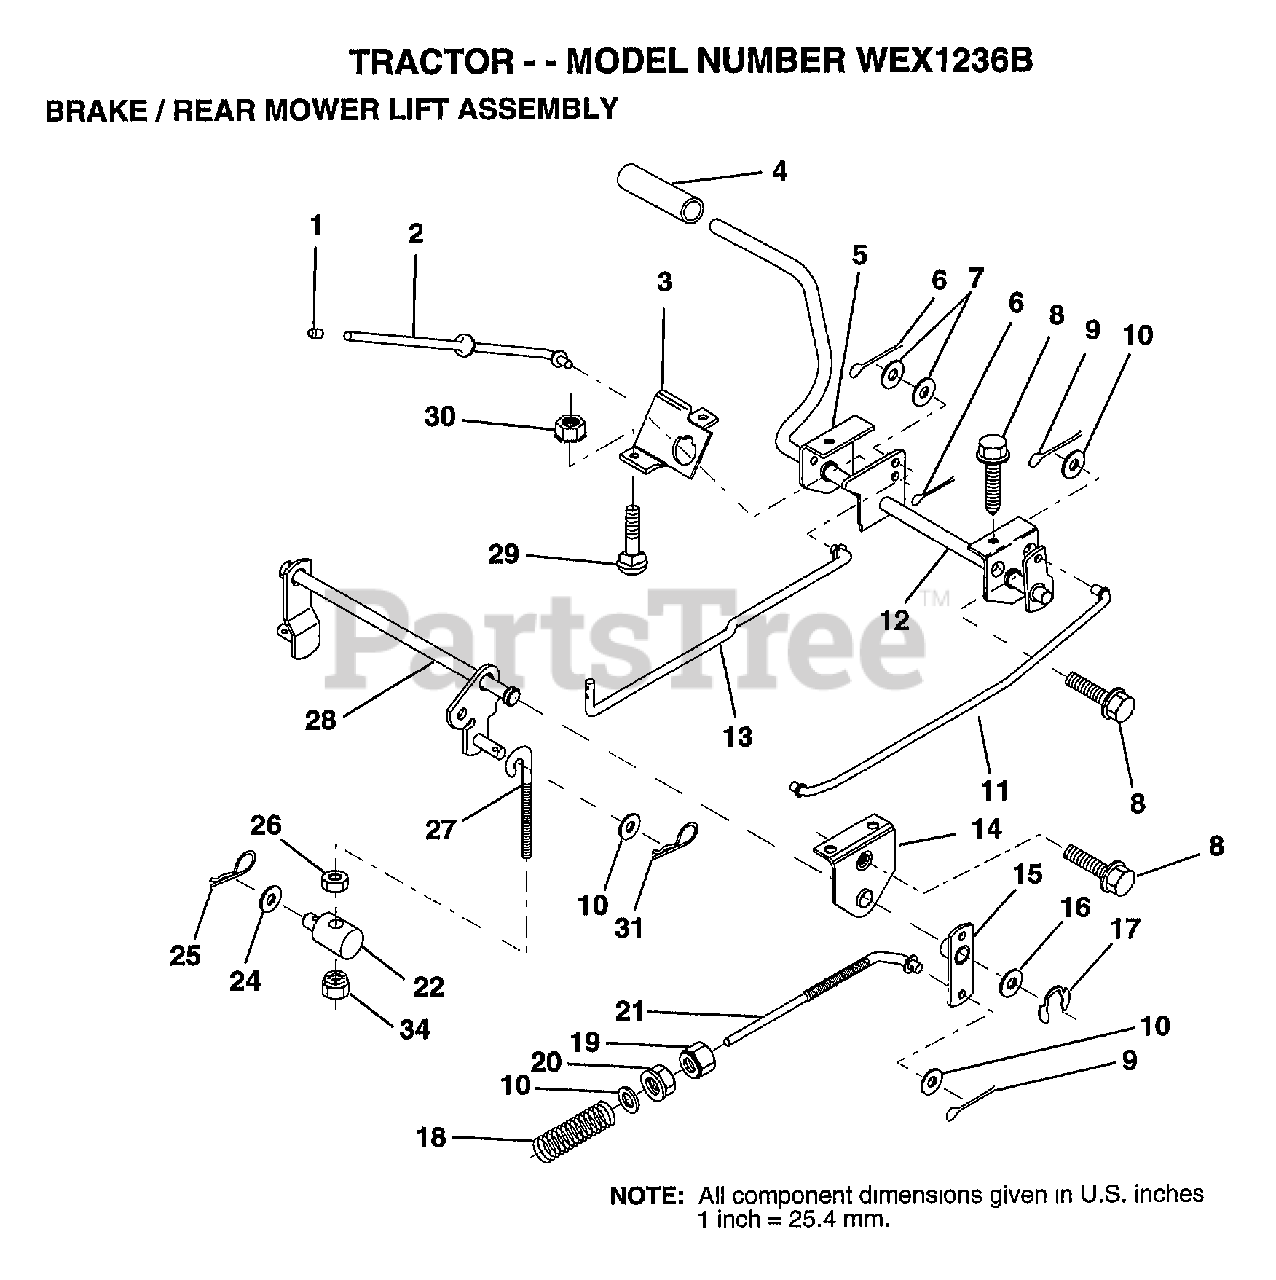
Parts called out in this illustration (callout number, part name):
1	PLUNGER CAP T
2	"ROD,PARK BRAKE"
3	"BRKT,PARK BRAKE"
4	FOOT PEDAL COVER
5	"BRKT,CLU PEDAL LH"
7	WASHER
8	SCREW LT
9	COTTER PIN
10	WASHER
11	"ROD,FRT BRAKE"
12	PEDAL ASM CL/BK36
13	"ROD,CLUTCH"
14	"BRKT,LIFT SHAFT"
15	PVT BRAKE ARM ASM
16	WASHER T
17	KLIP RING
18	SPRING ROD BRAKE
19	NUT
20	NUT
22	TRUNNION.LIFT.
24	WASHER
25	SPRING.RETAINER
26	LOCKNUT
27	"LINK, MOWER REAR"
28	LIFT ASM MOW REAR
31	RETAINER.SPRING
